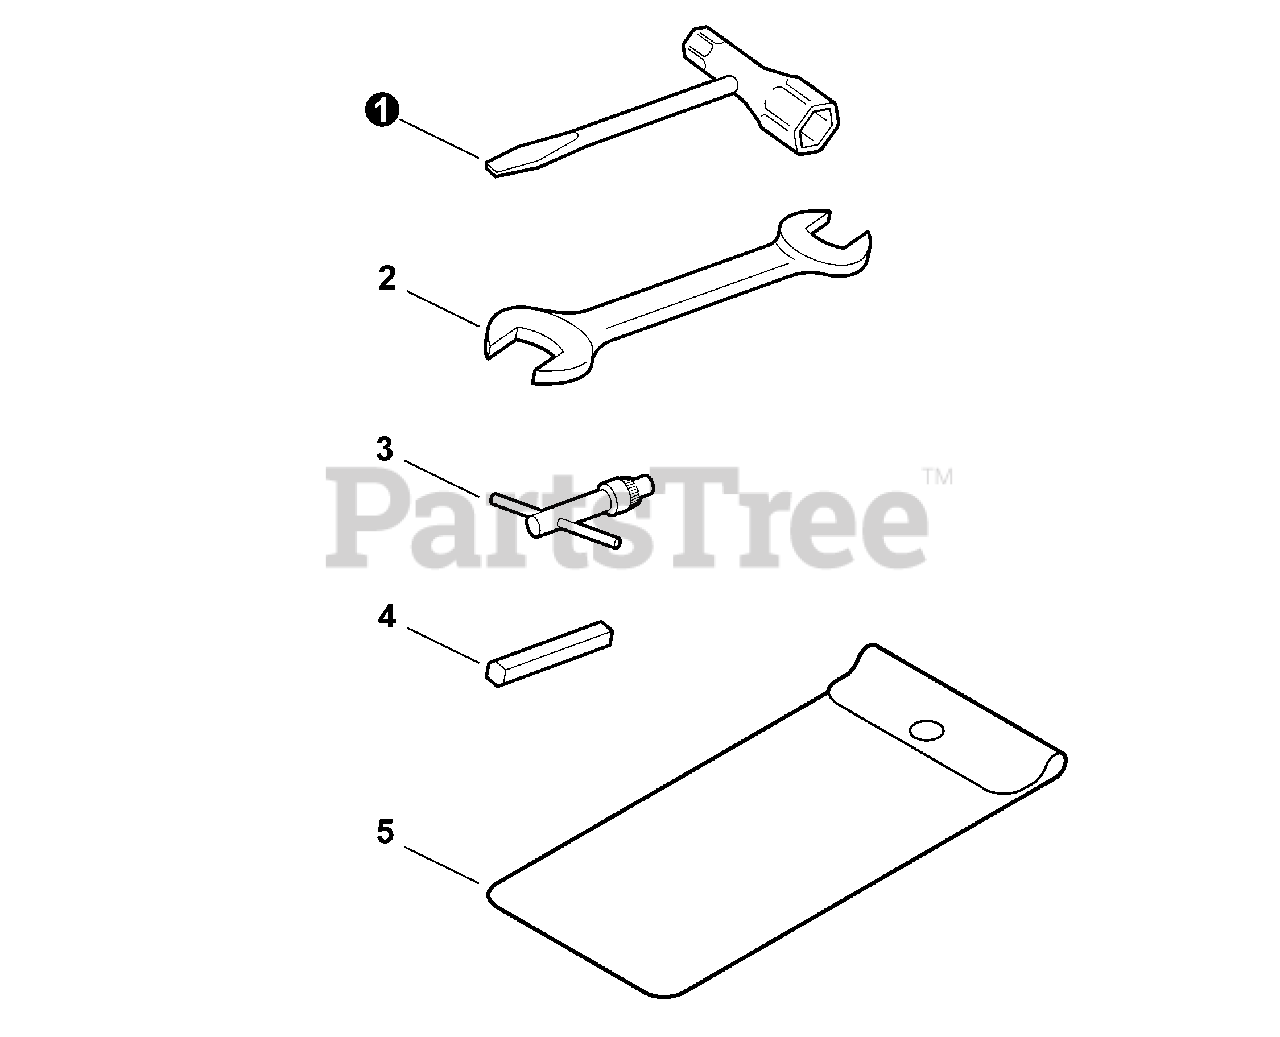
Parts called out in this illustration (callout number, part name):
1	T-WRENCH - 10×19mm
2	SPANNER - 17×19mm
3	KEY, CHUCK
4	BAR, HEX
5	BAG,TOOL
